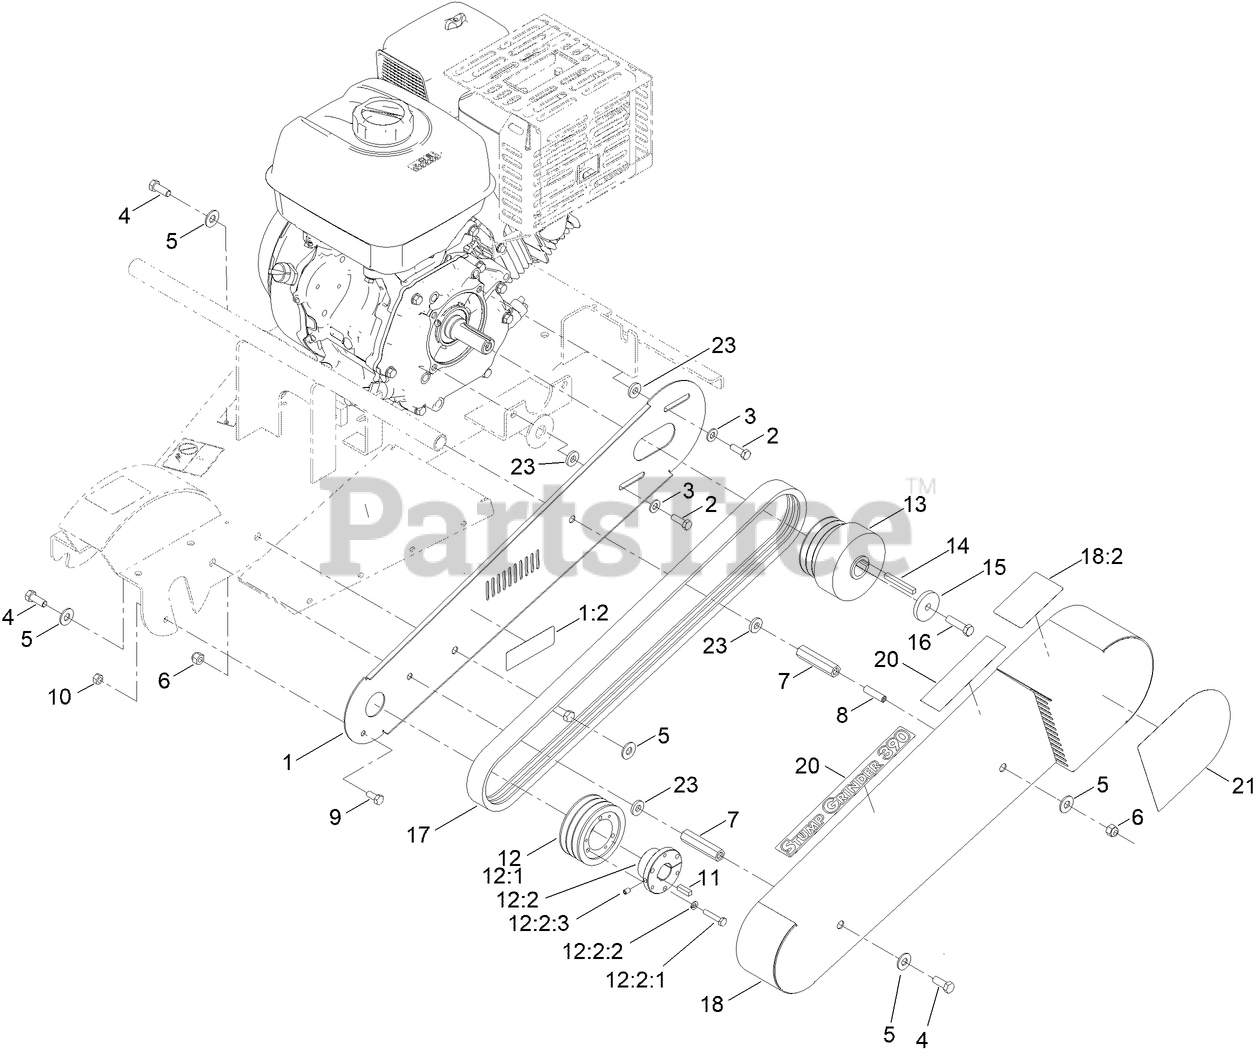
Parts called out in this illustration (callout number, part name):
1	PLATE-GUARD
1:2	DECAL-WARNING
2	SCREW-HH, PATCH
3	WASHER-FLAT
4	SCREW-HH
5	WASHER-FLAT
6	NUT-LOCK, NI
7	SPACER-GUARD
8	SCREW-SET, HSH
9	SCREW-HH
10	NUT-HEX
11	KEY-SQUARE
12	SHEAVE ASM
12:1	PULLEY
12:2	BUSHING
12:2:1	SCREW-HH
12:2:2	WASHER-LOCK
12:2:3	SCREW-SET, HSH
13	CLUTCH
14	KEY-SQUARE
15	WASHER-PLAIN
16	SCREW-HH
17	BELT-3V
18	BELT GUARD ASM
18:2	DECAL-CAUTION
23	SPACER
